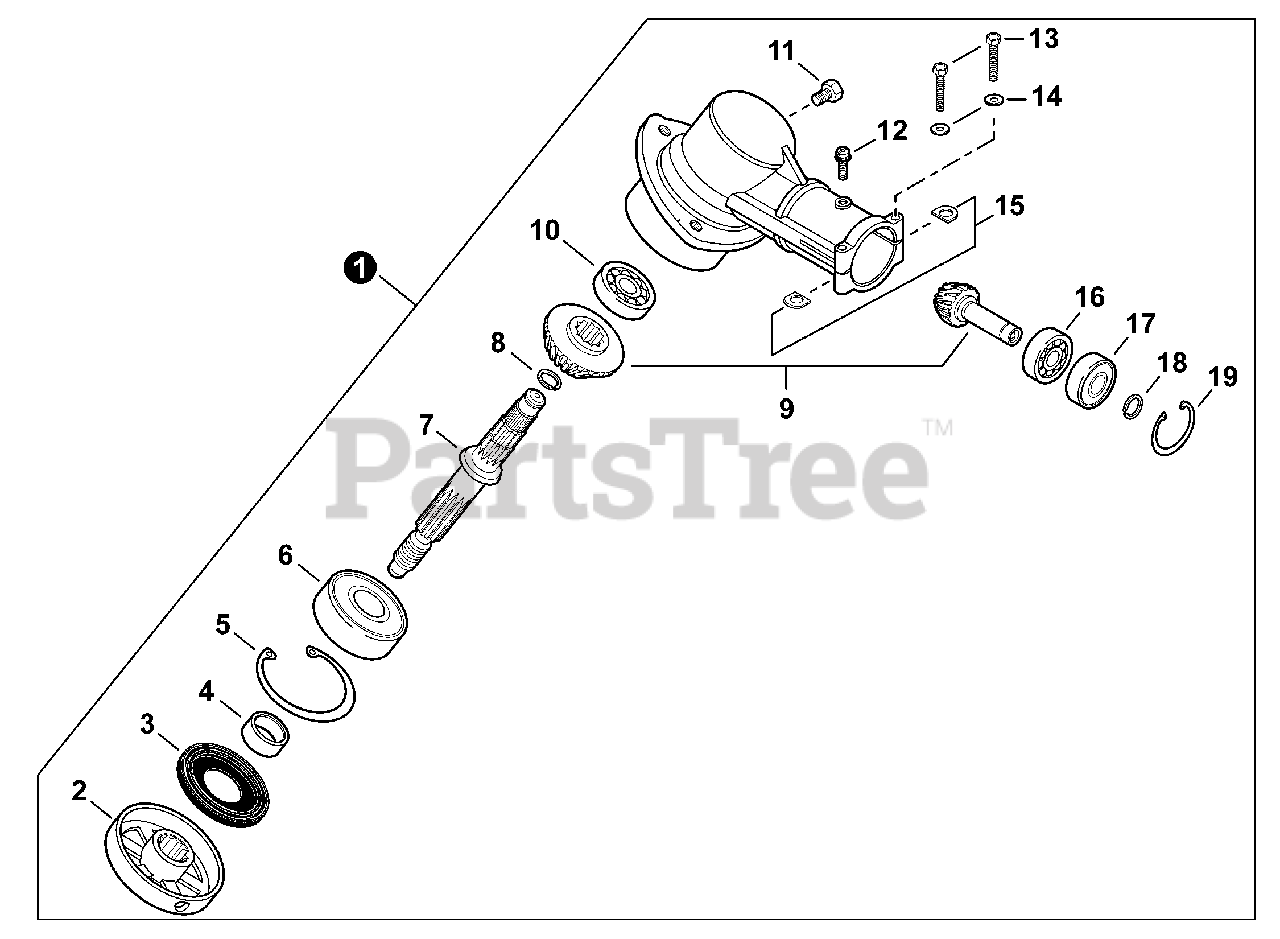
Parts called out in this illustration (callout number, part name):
1	GEAR CASE ASSY
2	PLATE, ADAPTOR - UPPER
3	SEAL, OIL 22
4	SPACER 11.8×15×9
5	RING, SNAP Ø32
6	BEARING, BALL 6201
7	SHAFT, GEAR
8	RING, SNAP Ø12
9	GEAR SET
10	BEARING, BALL 609
11	BOLT M8×1.25
12	SCREW 5×10
13	BOLT 5×35 SP
14	WASHER, FLAT 5.5×10×0.8
15	D-WASHER
16	BEARING, BALL 6900
17	BEARING, BALL 6900-Z
18	RING, SNAP Ø10
19	RING, SNAP Ø22
